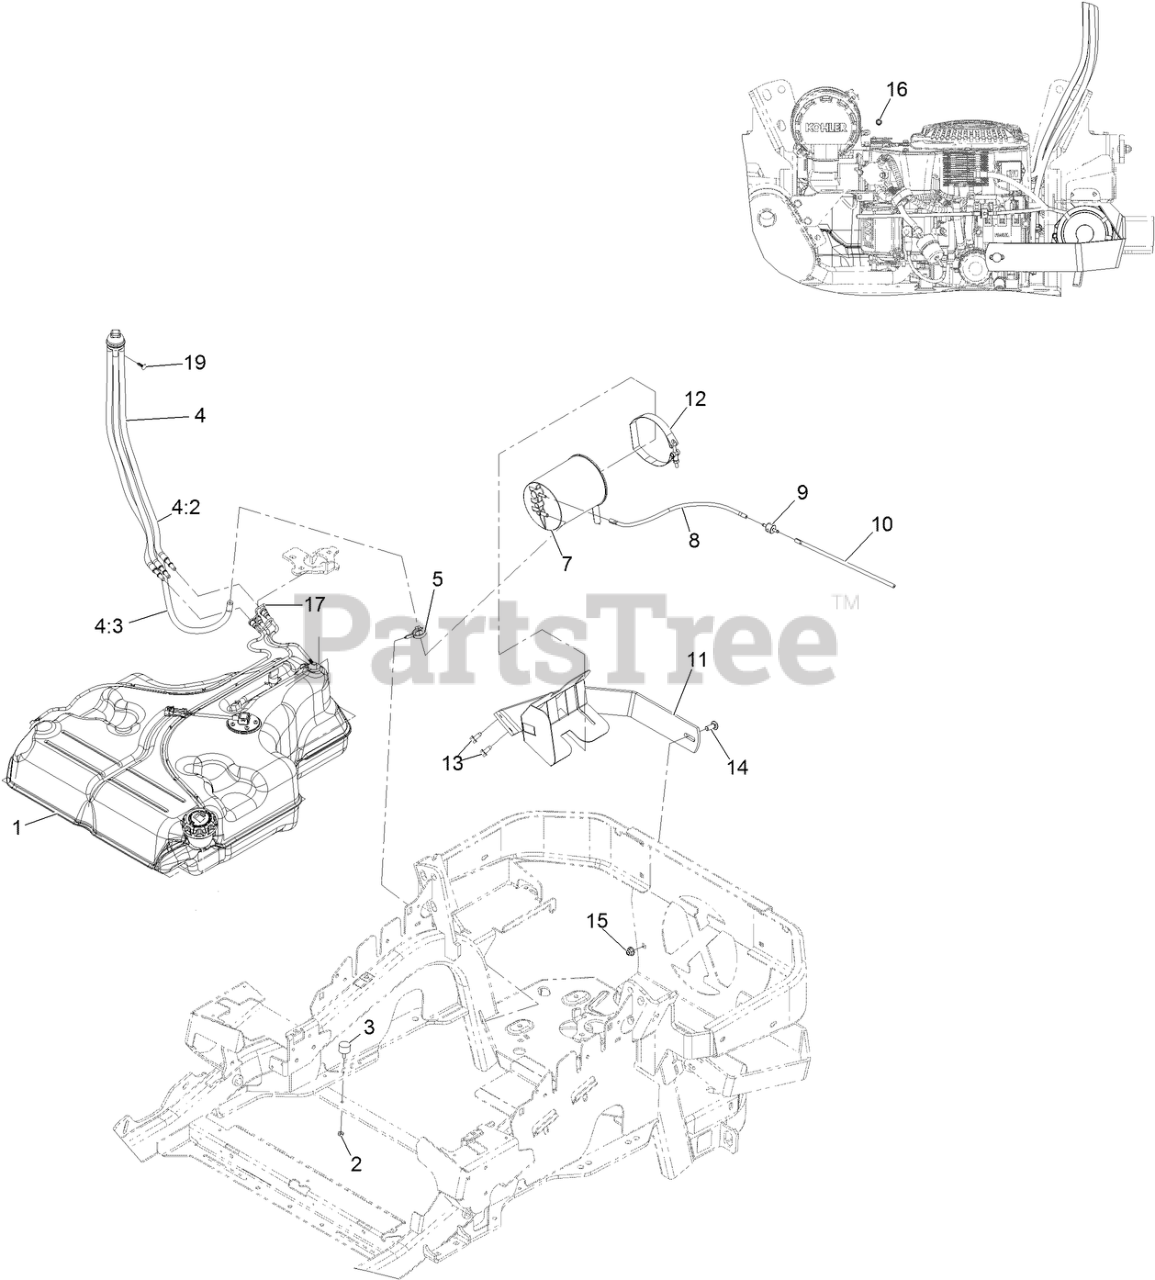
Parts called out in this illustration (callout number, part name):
1	FUEL TANK ASM
2	NUT-JAM
3	BUMPER
4	FUEL MANIFOLD VENT ASM
4:2	HOSE-FUEL
4:3	HOSE-FUEL
5	CLAMP-HOSE
7	CANISTER-CARBON, 1200CC
8	HOSE-VENT, FORMED
9	VALVE-CHECK, VACUUM
10	HOSE-VENT, FORMED
11	MOUNT-CANISTER
12	CLAMP, T-BOLT
13	SCREW-HWHTF
14	SCREW-CARR
15	NUT-HF, NI
16	PLUG-PORT
17	RETAINER-LINE, VAPOR
19	PLUG-PLASTIC
